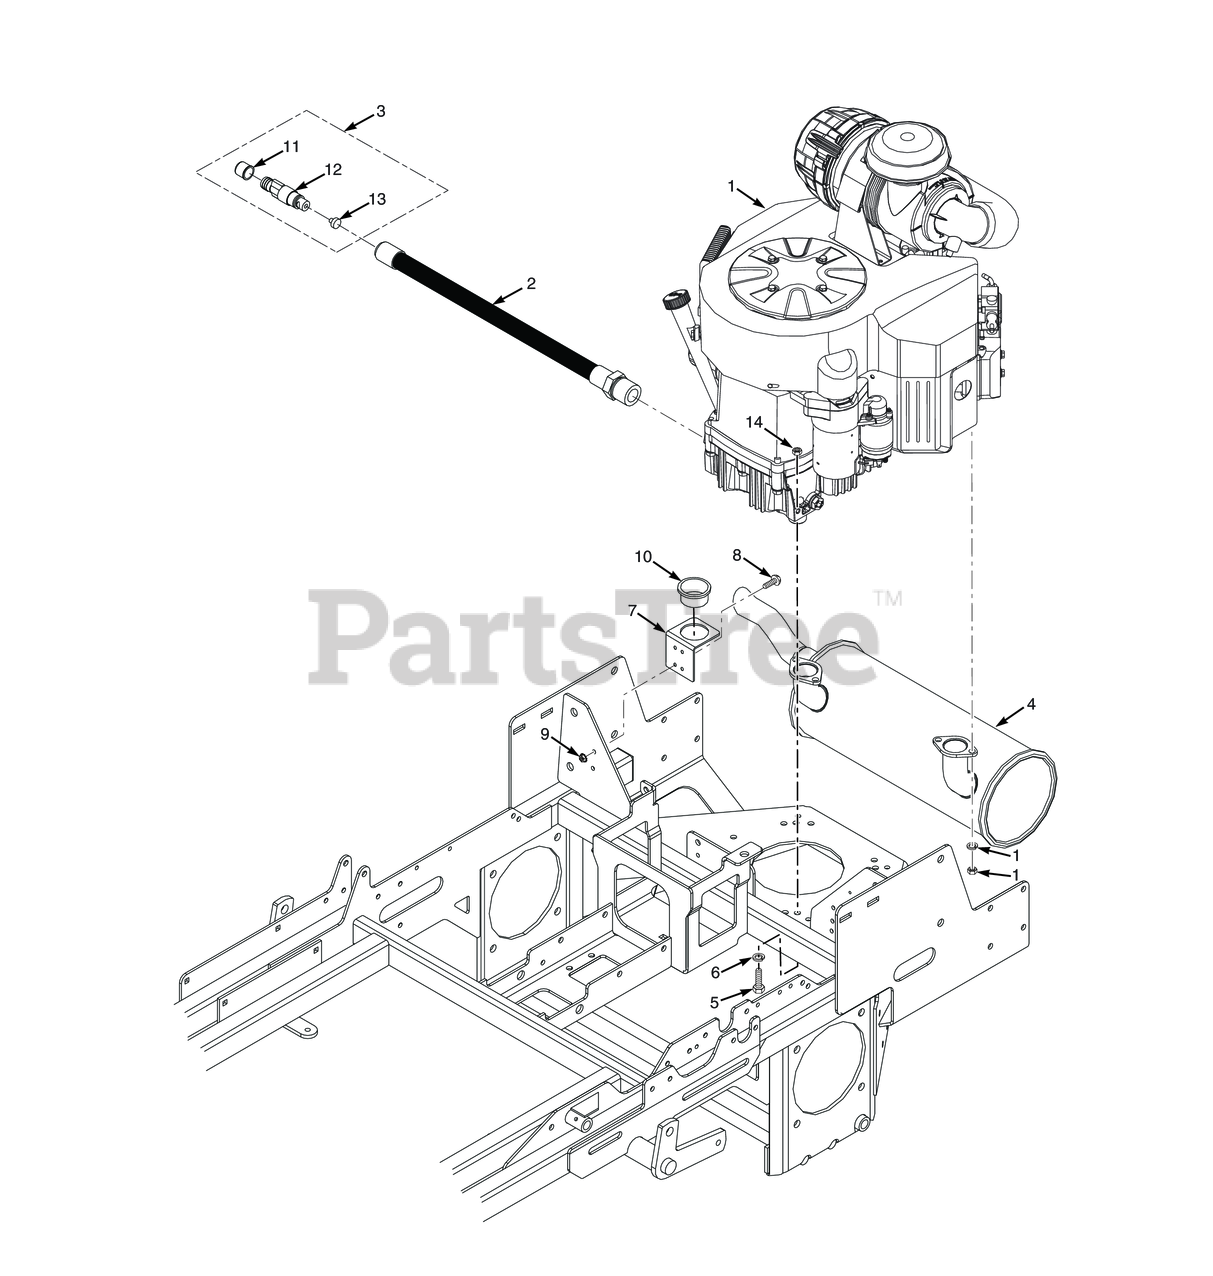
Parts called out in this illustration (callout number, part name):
1	Engine, Kawasaki 38FX-EFI (FX1000)
1	Engine, Briggs & Stratton 37 BV-EFI (61E8770002J1)
2	Hose Assembly, Engine Oil Drain - Kawasaki FS/FX
3	Valve Assembly, Oil Drain
4	Muffler, Kawasaki - FX921
5	Bolt, Hex Head 3/8-16 x 1-1/4", Kawasaki FX / FS
6	Lockwasher, 3/8" Spring, Kawasaki FX / FS
7	Bracket, Oil Drain Hose
8	SCR,#8-32 X .625 HX WSHR HD SLOTTED
9	Nut, Elastic Stop #8-32
10	Bushing, Thick Panel Snap
11	O-Ring
12	O-Ring
